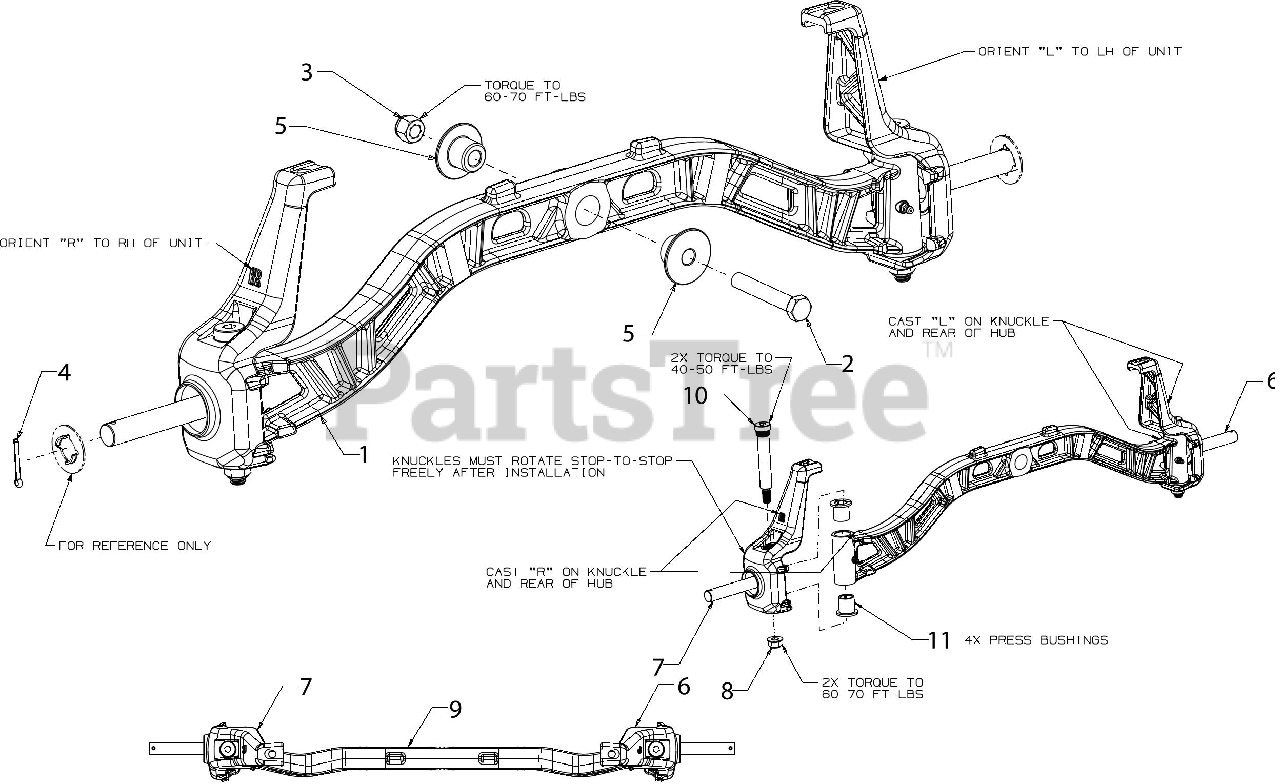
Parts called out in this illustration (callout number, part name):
1	FRONT AXLE ASSEMBLY
2	HEX SCREW 1/2-13 x 3.00
3	HEX LOCK NUT NYLON
4	COTTER PIN-5/32 DIA
5	SHOULDER SPACER
6	EPS STEERING AXLE ASSEMBLY (LH)
7	EPS STEERING AXLE ASSEMBLY (RH)
9	CAST PIVOT BAR AXLE
10	SHOULDER BOLT .75X3.92 1/2-13
11	FLANGE BEARING .75 x 1.00 x 1.12
